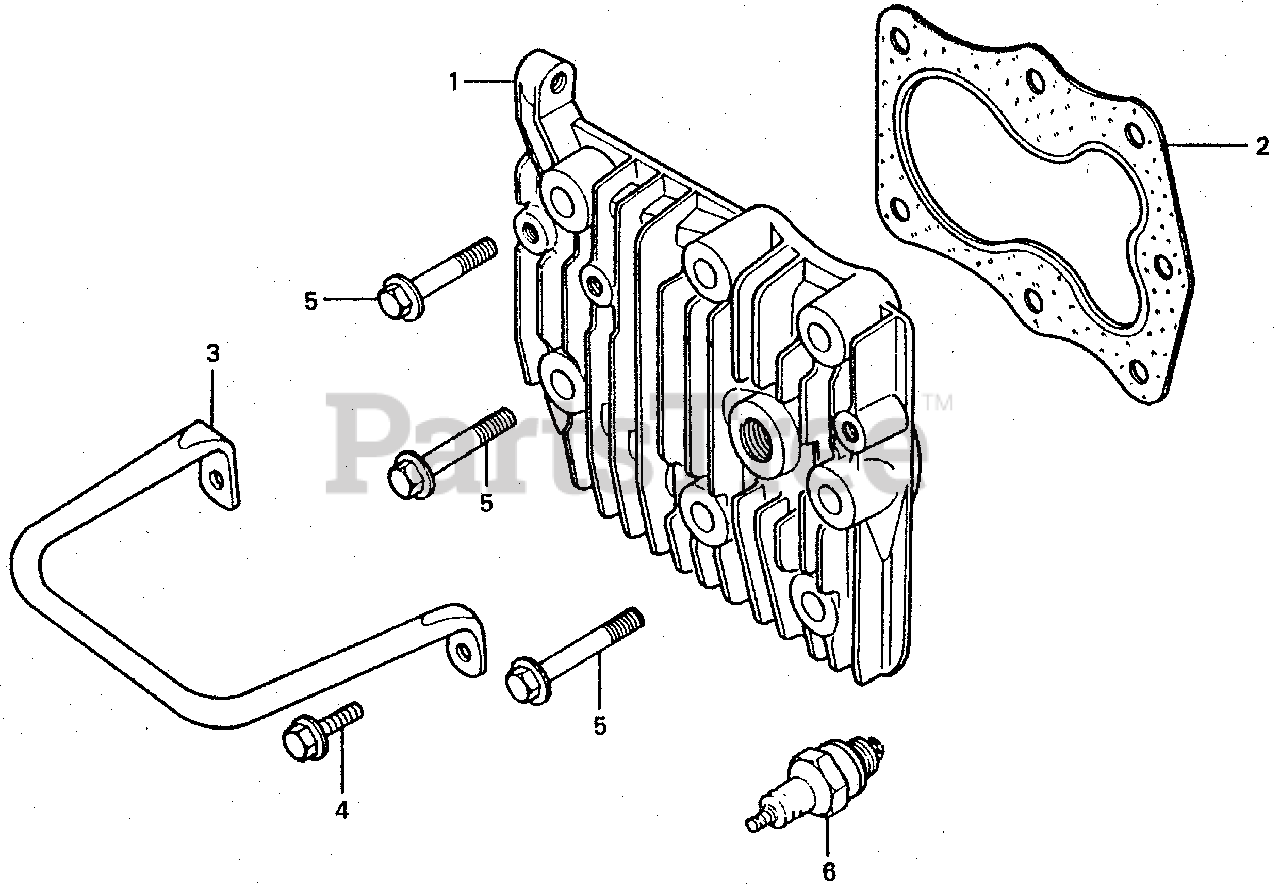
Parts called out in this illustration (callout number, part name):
1	CYLINDER HEAD (NOT AVAILABLE)
2	GASKET, CYLINDER HEAD
3	GUARD, PLUG
4	BOLT, FLANGE (6X12) (CT200)
5	BOLT, FLANGE (8X45)
6	SPARK PLUG (BPM6A-10) (NGK)
